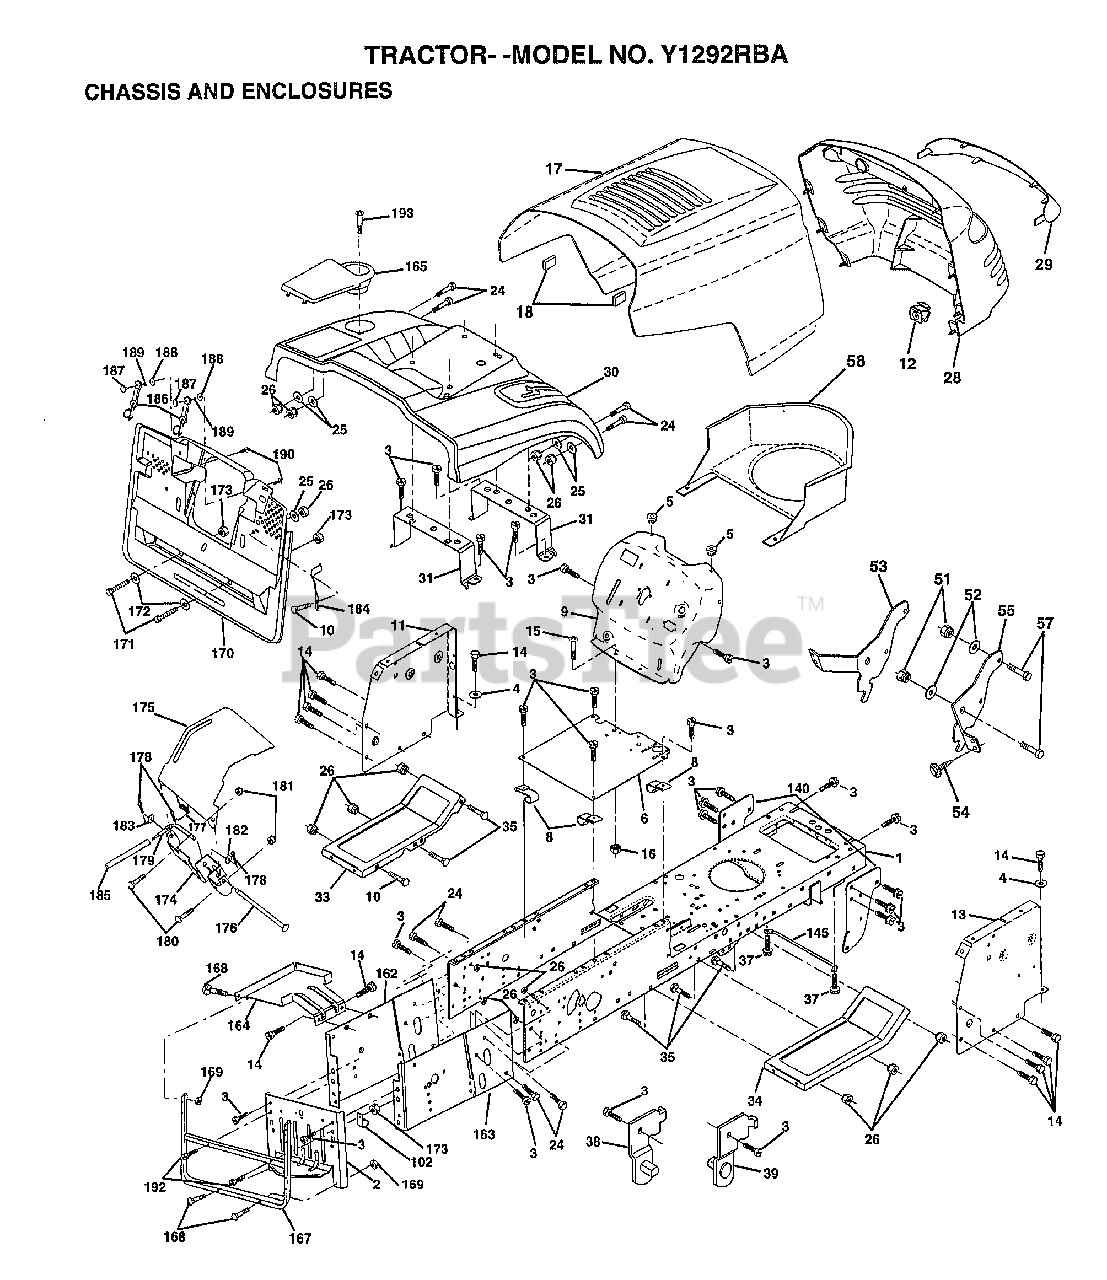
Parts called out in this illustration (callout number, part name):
1	CHASSIS.STAMPING
2	DRAWBAR.CRD
3	SCREW
4	WASHER
5	BUMPER-HOOD/DASH
6	SADDLE
8	"CLIP,INSULATOR"
9	DASH.SILKSCREEN
11	"PANEL-DASH,LH"
12	CLIP.TINNERMAN
14	SCREW LT
15	SCREW
17	HOOD.STEEL.ASSY
24	BOLT
25	WASHER
26	NUT
28	GRILLE-MS428
29	LENS.GRILLE.PRIVATE LABEL
30	FENDER.FEAR.CRD.RED
31	BRKT.SUPT.FENDER.CRD
33	FOOTREST.LH.LT/GT
34	FOOTREST.RH.LT/GT
35	BOLT
37	SCREW LT
38	BRACKET ASM LH
39	BRACKET ASM RH
51	NUT
52	WASHER
53	BRACKET.GRILLE.LH
54	SCREW.HEX.WS.HD
55	BRACKET.GRILLE.RH
58	AIR DUCT
102	CLIP T
140	BRKT SUSPENSION
145	"ROD POVOT,CHASSIS"
162	BRKT.EXT.CHASSIS.LH.CRD
163	BRKT.EXT.CHASSIS.RH.CRD
164	SUPPORT.BATTERY.CRD
165	COVER.BATTERY.CRD.BLACK.LT
167	SUPT.ASM.BACKPLATE
168	BOLT-RD HD SQ NK
170	COVER.BACKPLATE.BLACK
171	BOLT.HEX.3/8-16X2-1/2
173	NUT
174	BRKT.SWITCH.FBI.CRD
175	GRUARD.DOOR.REAR.CRD
176	HINGE PIN
177	SPRING.COVER.LH
179	ROD.PIVOT.FBI.CRD
182	WASHER.385X.625
183	WASHER
184	BRKT.ACTUATOR.BAG.CRD
185	TUBE.LEVER.SWCH.FBI.CRD
186	LATCH ASSY.BAGGER
187	WELDNUT
188	WASHER #10
189	LOCKWASHER
190	SCREW
192	SCREW LT
193	SCREW LT
